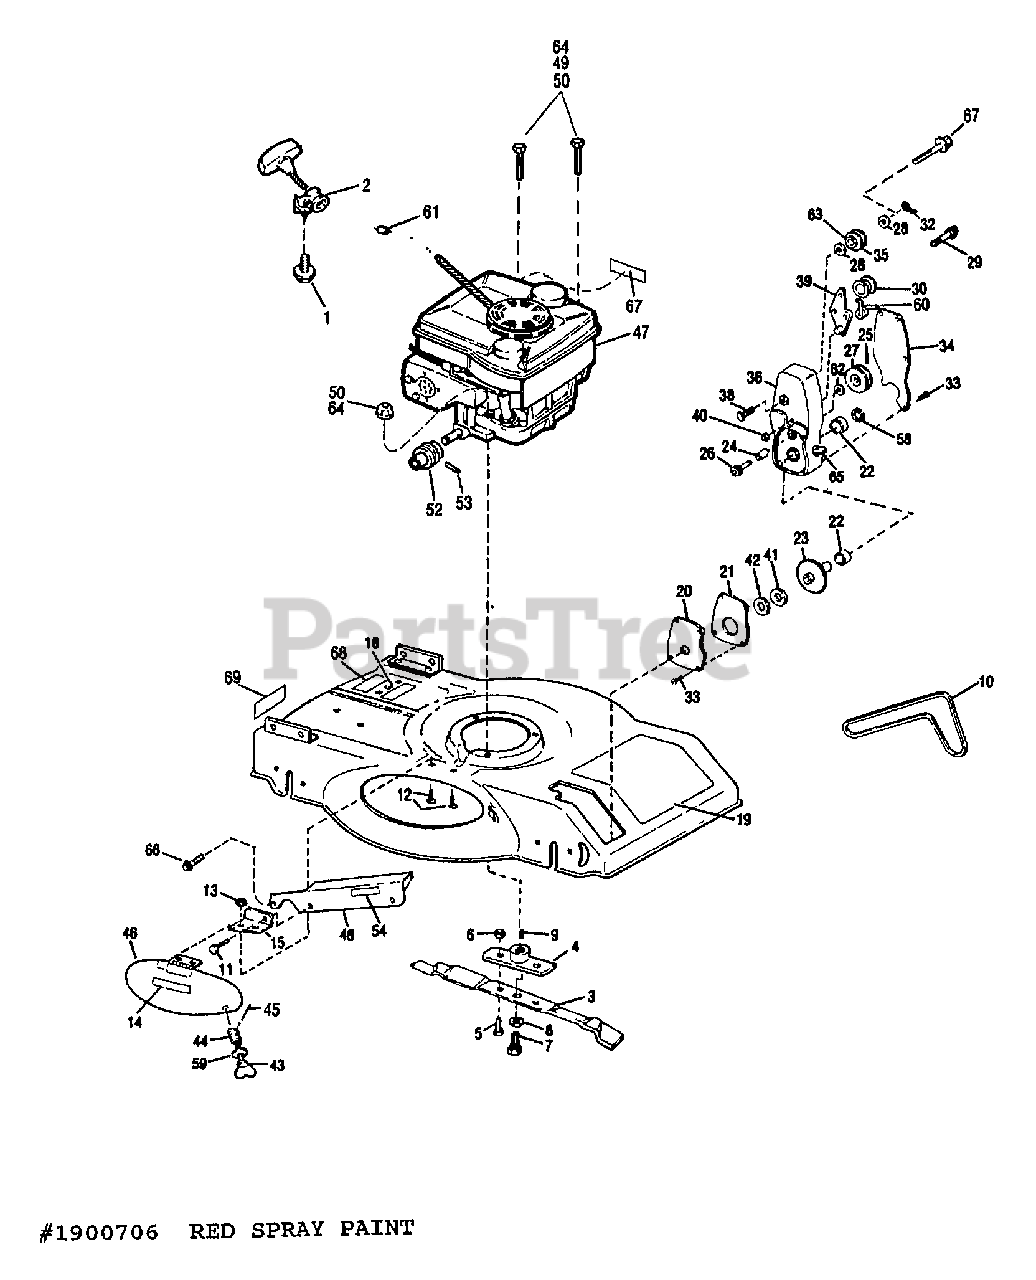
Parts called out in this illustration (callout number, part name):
1	SCR-HFLK {NOT 8656}
2	GUIDE-ROPE {NOT 8656}
3	BLADE-22" MULCHER
4	ASSM-BLADE COUPLING
5	SCR-HH 3/8-16X1.0 G5 ZP
6	NUT-LOCK 3/8-16
7	SCR-SHOULDER
8	WASHER-LK .5
9	KEY-WOODRUFF
10	BELT-DRIVE
11	SCR-SHOULDER
12	SCR-CARR 1/4-20X.375
13	NUT-HF/LK 1/4-20 ZP
14	DECAL-CAUTION
15	BRKT-SUPPORT
18	DECAL-CUTTING HEIGHT
19	DECAL-LOGO
20	COVER-GEAR CASE BOTTOM
21	GASKET-GEAR CASE
22	BEARING-BRONZE
23	ASSM-GEAR SHAFT
24	BEARING-BRONZE
25	PIN-DRIVE .218X1.12
26	ASSM-STEEL PINION SHAFT
27	SHEAVE
28	FLAT WASHER
28	WASHER-FLAT 1.0X.516X.031 (A)
29	SCR-HH 3/8-16X1.0 G5 ZP
30	IDLER-FLAT
32	COTTER PIN, 1/8 X 3/4 (A)
32	PIN-COTTER .125 X .75 ZP
33	SCR-HW M10-24X.5 STH ZP
34	COVER-GEAR CASE TOP
35	SHEAVE
35	KIT-IDLER PULLEY (A)
35	SHEAVE (B)
36	KIT-GEAR CASE
38	SCR-SHOULDER
39	ASSM-IDLER ARM
40	NUT-PUSH 3/8 ZP
41	WASHER-1.5X.755X.062
42	WASHER-FELT
43	PIN-CHUTE LOCK
44	SPRING-COMPRESSION
45	PIN-ROLL .093 DIAX.62
46	COVER-DISCHARGE W/DECAL (INCL. REF. NO. 14)
47	BRIGGS & STRATTON ENGINE, 4.0 HP, 122782
47	BRIGSS & STRATTON ENGINE, 5.0 HP, 124782
47	BRIGGS & STRATTON ENGINE, 5.0 HP, 124787
48	ASSM-BELT COVER
49	SCR-HH 5/16-18X1.25 G5ZP
50	HEX TOPLOCK NUT
50	NUT-TOP/LK 5/16-18 ZP (A)
52	SHEAVE
53	PIN-ROLL
54	DECAL-FRONT WHEEL DRIVE
58	RING-GRIP EXT .5 ID
59	WASHER-.75X.312X.065 ZP
60	SPRING-TORSION
61	STOP-STARTER ROPE {NOT 8656}
62	WASHER-SHIM
63	BALL BEARING
63	BEARING-BALL (A)
64	HEX HD. CAPSCREW, THD. FORMING, 3/8-16X1
64	SCR-HH 5/16-18X2.25 G5ZP (A)
64	SCR-HH 3/8-16X1.0 THDFM (B)
65	FITTING-GREASE 1/4-28X2.00
66	SCR-FLANGE 1/4-20X3/4 GR5
67	HEX HD. CAPSCREW, 5/16-18 X 7/8
67	SCR-HH 5/16-18X.875 G5 ZP (A)
68	DECAL-U.S.A.
69	DECAL-SOUND LEVEL
70	DECAL-ENGINE (SEARS) {RS}
